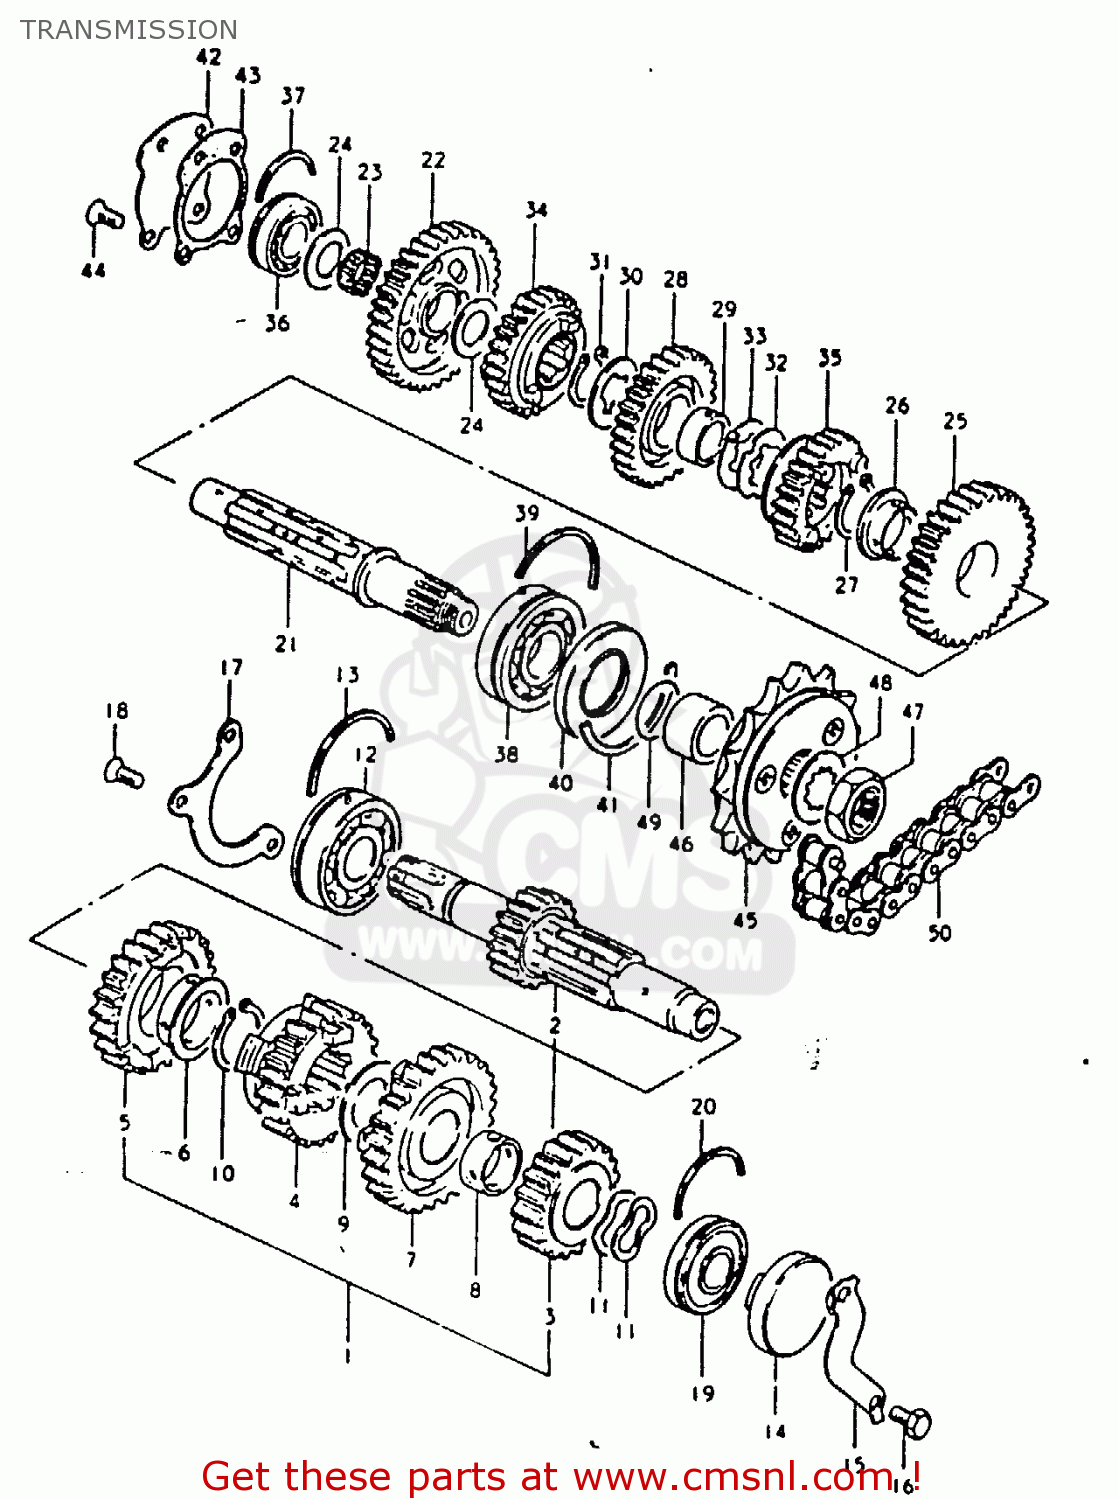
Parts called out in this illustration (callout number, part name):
1	SHAFT,COUNTER
2	SHAFT,COUNTER
3	GEAR,SECOND DRIVE
4	GEAR,3RD DRIVE(NT:21)
5	GEAR,FOURTH DRIVE
6	BUSH(28X32X2)
7	GEAR,FIFTH DRIVE
8	BUSHING
9	WASHER
10	CIRCLIP
11	WASHER
12	BEARING(25X62X17)
13	C-RING
14	PLUG
15	RETAINER,CL PUSH ROD OIL SEAL
16	BOLT
17	RETAINER,CNTR SHAFT BEARING
18	SCREW
19	BEARING(20X47X14)
20	C RING
21	SHAFT,DRIVE
22	GEAR,FIRST DRIVEN (NT:35)
23	BEARING(20X24X10).8
24	WASHER
25	GEAR,SECOND DRIVEN
26	BUSH(28X32X2)
27	CIRCLIP
28	GEAR,THIRD DRIVEN
29	BUSH,3RD DRIVEN GEAR
30	WASHER,LOCK
31	CIRCLIP
32	WASHER,LOCK
33	WASHER
34	GEAR,FOURTH DRIVEN
35	GEAR,FIFTH DRIVEN
36	BEARING
37	C RING
38	BEARING(25X62X17)
39	C-RING
40	SEAL,OIL(32X62X7)
41	C RING
42	PLATE,DRIVE SHAFT
43	GASKET,DRIVESHAFT PLATE (MCA)
44	SCREW
45	SPROCKET,ENGINE
46	SPACER(25X32X18.6)
47	NUT
48	WASHER
49	O RING(D:1,ID:24.5)
50	CHAIN,DRIVE(DID630YL,96LE)
